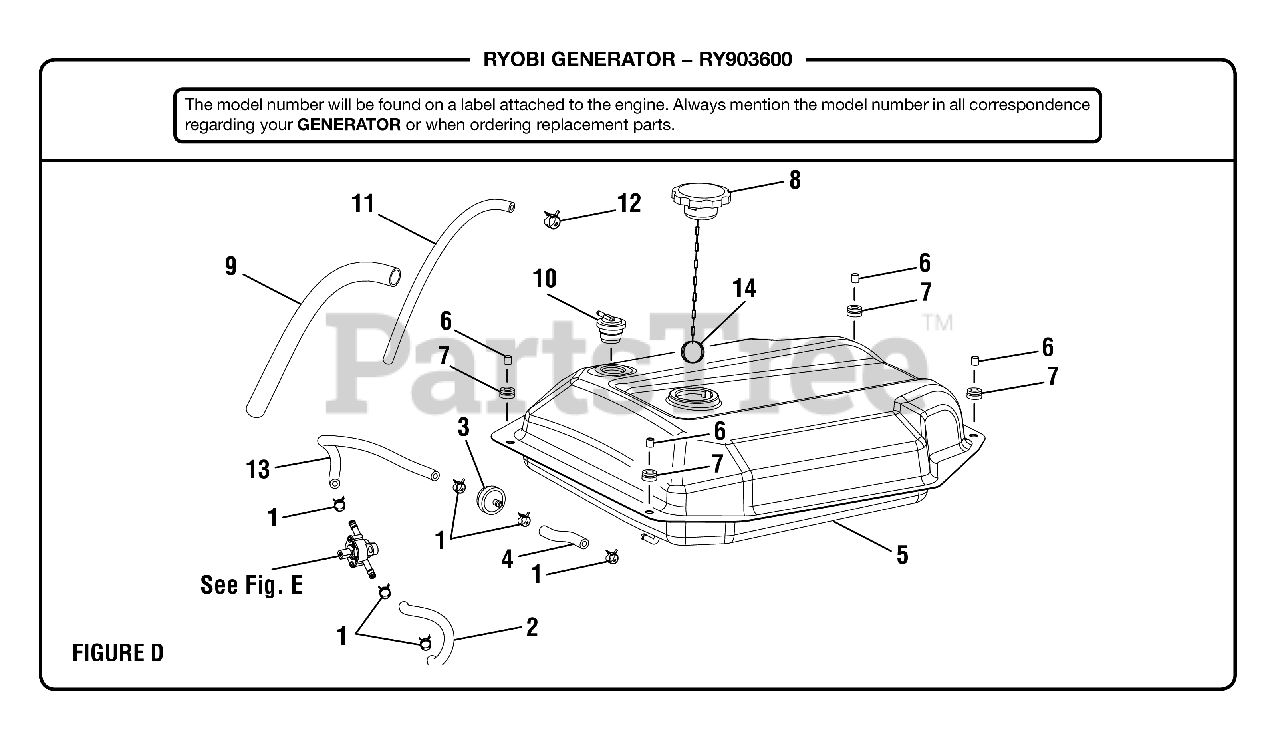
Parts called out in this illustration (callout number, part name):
1	Fuel Line Clamp (1/2 in.).
2	Fuel Hose (175 mm)
3	Fuel Filter Inline (1/4 in.)
4	Fuel Hose (80 mm)
5	Fuel Tank
6	Spacer (Fuel Tank Isolator)
7	Bushing (Fuel Tank Isolator)
8	Fuel Cap Assembly
9	Fuel Hose Cover (200 mm)
10	Fuel Tank Vapor Vent
11	Vapor Hose (330 mm)
12	Fuel Line Clamp (7/16 in., BM903611)
13	Fuel Hose (300 mm)
14	Ring Clip
